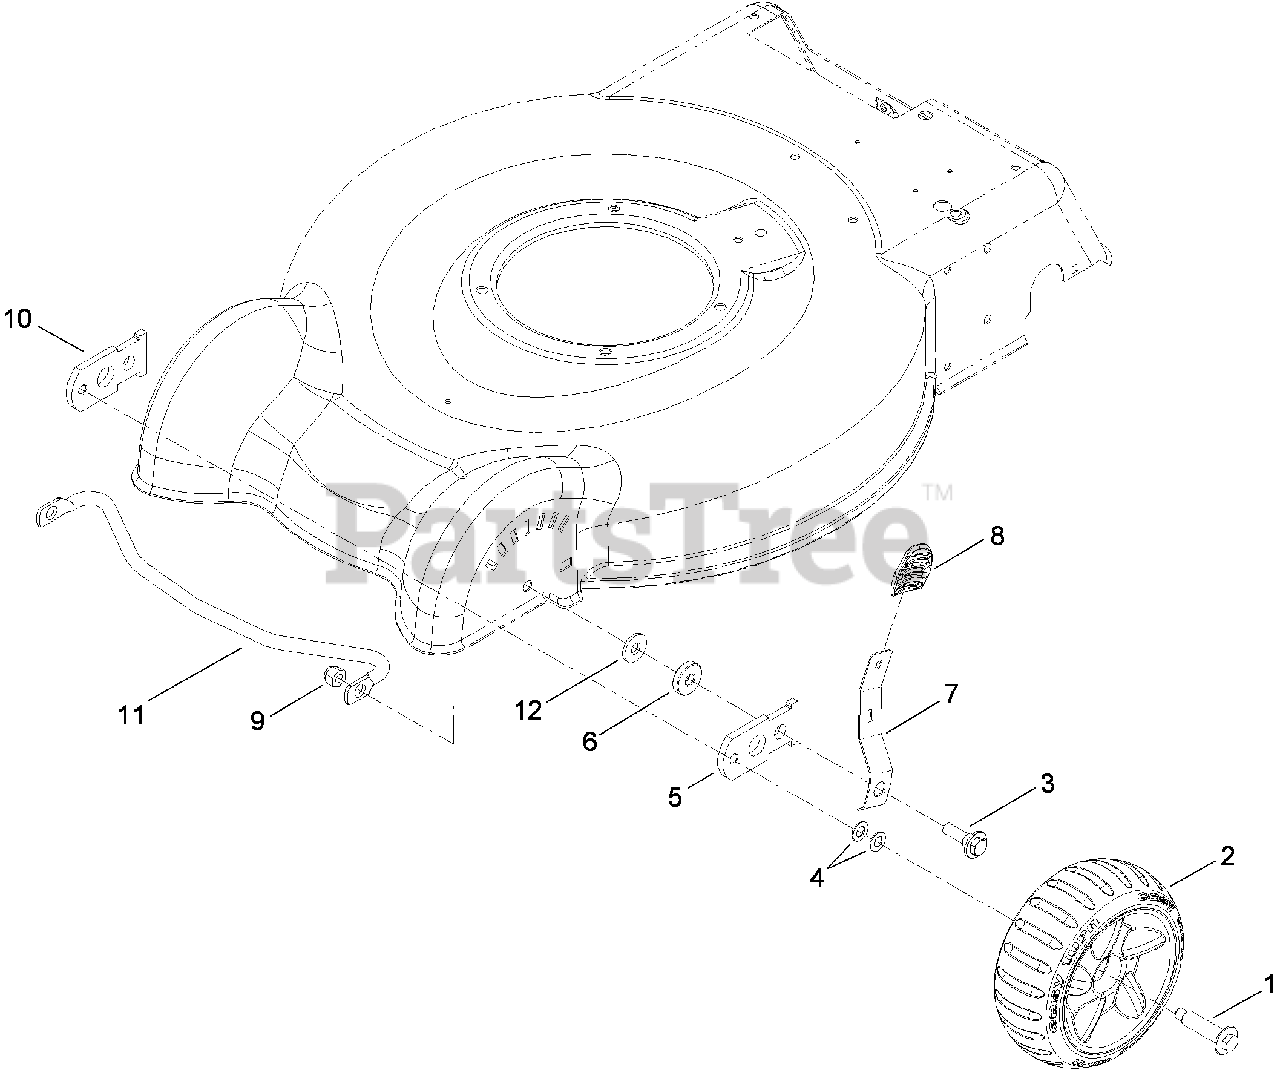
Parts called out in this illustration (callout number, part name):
1	BOLT-SHOULDER
2	7 INCH FRONT WHEEL ASM
3	BOLT-SHOULDER
5	ARM-PIVOT, RH
7	ARM-SPRING, FRONT
8	Knob-Lever, HOC
9	NUT-LOCK, NI
10	ARM-PIVOT, LH
11	BRACE-FRONT
12	WASHER-HARDENED
